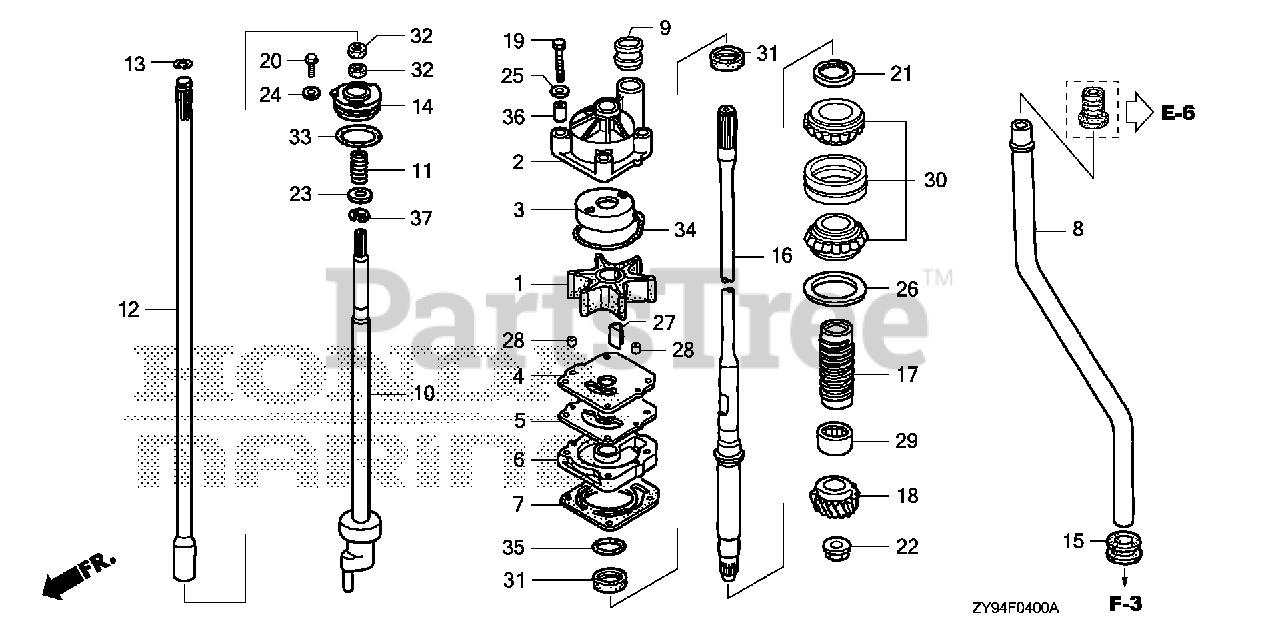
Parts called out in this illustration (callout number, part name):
1	IMPELLER, PUMP
2	HOUSING, IMPELLER
3	LINER, PUMP
4	COVER, IMPELLER
5	GASKET B, IMPELLER
6	HOUSING, WATER PUMP
7	GASKET, WATER PUMP
8	TUBE, WATER (L)
9	RING, WATER TUBE SEAL
10	ROD, SHIFT (L)
11	SPRING, SHIFT ROD
12	ROD A, SHIFT (L)
13	RING, STOPPER
14	HOLDER, SHIFT ROD
15	GROMMET, EXTENSION CASE
16	SHAFT, VERTICAL (L)
17	SLINGER, OIL
18	GEAR, PINION (12T)
19	BOLT, HEX. (8X55)
20	BOLT, FLANGE (6X12) Use from Frame SN 1005249.
21	NUT, LOCK (64MM)
22	NUT, HEX. (16MM)
23	WASHER, PLAIN (12MM)
24	WASHER, PLAIN (6MM)
25	WASHER (8MM)
26	SHIM A, GEAR (0.10)
26	SHIM B, GEAR (0.15)
26	SHIM C, GEAR (0.30)
26	SHIM D, GEAR (0.50)
27	KEY, WOODRUFF
28	PIN, DOWEL (6X10)
29	BEARING, NEEDLE (1-1/8X1-1/2X1-1/4)
30	BEARING, TAPER ROLLER (30X62X40)
31	SEAL, WATER (23X36X6) Use up to Frame SN 1300340.
32	SEAL, WATER (12X21X6)
33	O-RING (49.4X3.1)
34	O-RING, WATER PUMP
35	O-RING (58.5X3.5)
36	COLLAR, DISTANCE
37	E-RING (10MM)
